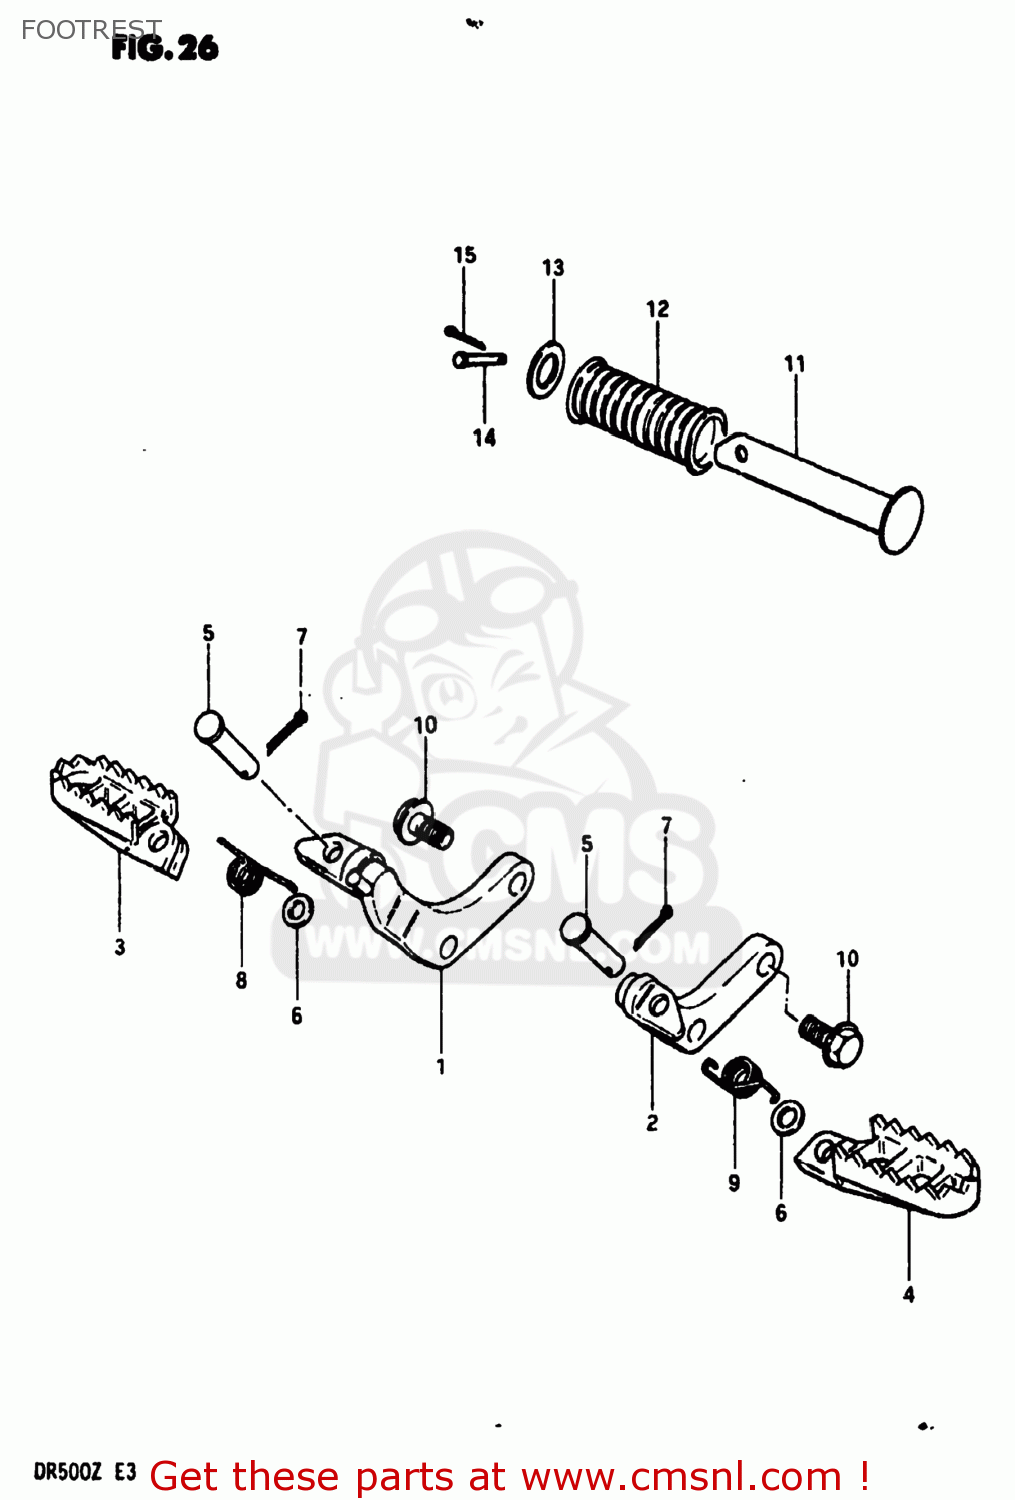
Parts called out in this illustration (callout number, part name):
1	BAR,FRONT FOOTREST
2	BAR,FRONT FOOTREST,LEFT
3	FOOTREST,RIGHT
4	FOOTREST
5	PIN
6	WASHER
7	PIN 20X20
8	SPRING
9	SPRING
10	BOLT(10X25)
